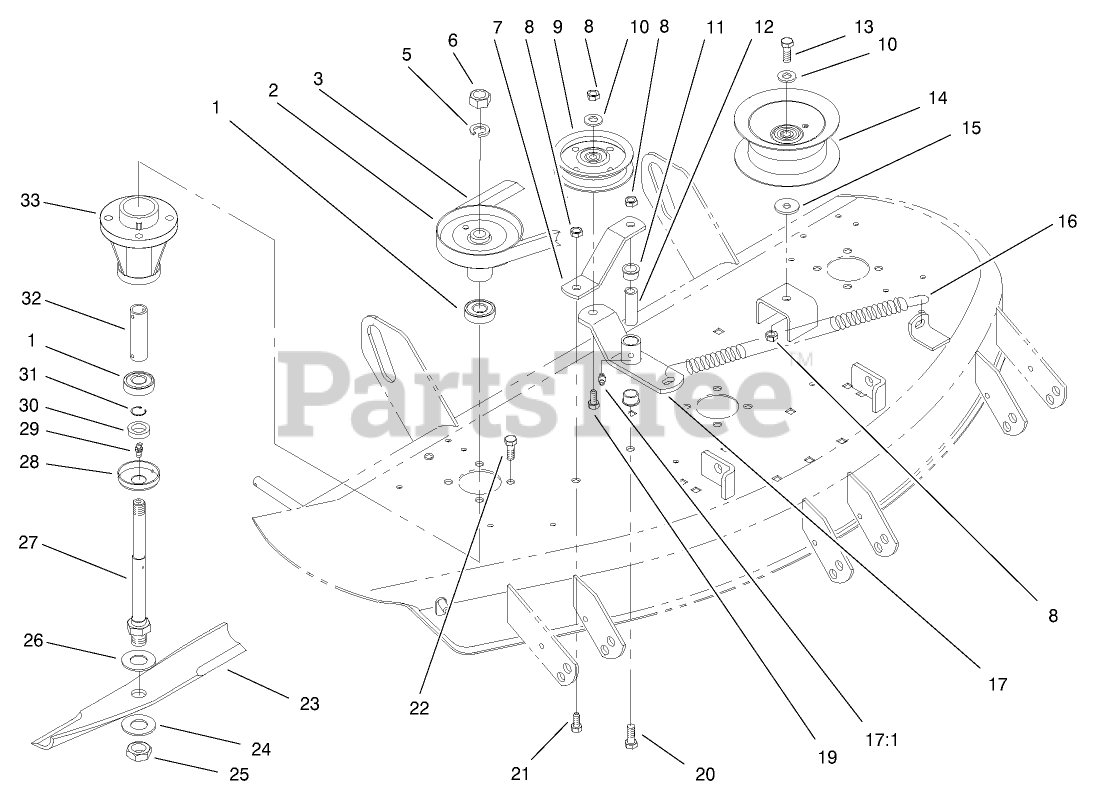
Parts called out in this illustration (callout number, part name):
1	BEARING-BALL
2	PULLEY
3	V-BELT
5	WASHER-LOCK
6	NUT-JAM
7	STRAP-BRACE
8	NUT-LOCK, NI
9	PULLEY-IDLER, FLAT
10	WASHER-FLAT
11	BUSHING
12	SPACER
13	SCREW-HH
14	PULLEY-IDLER
15	WASHER
16	SPRING-EXTENSION
17	ARM-IDLER
17:1	FITTING-GREASE
19	SCREW-HH
20	SCREW-HH
21	SCREW-HH
22	SCREW-HH
23	BLADE KIT (3 PACK)
24	WASHER-FLAT
25	NUT-JAM
26	WASHER-FLAT
27	SHAFT-SPINDLE
29	FITTING-GREASE
30	SPACER-BLADE
31	RING-RETAINING
33	HOUSING-SPINDLE
